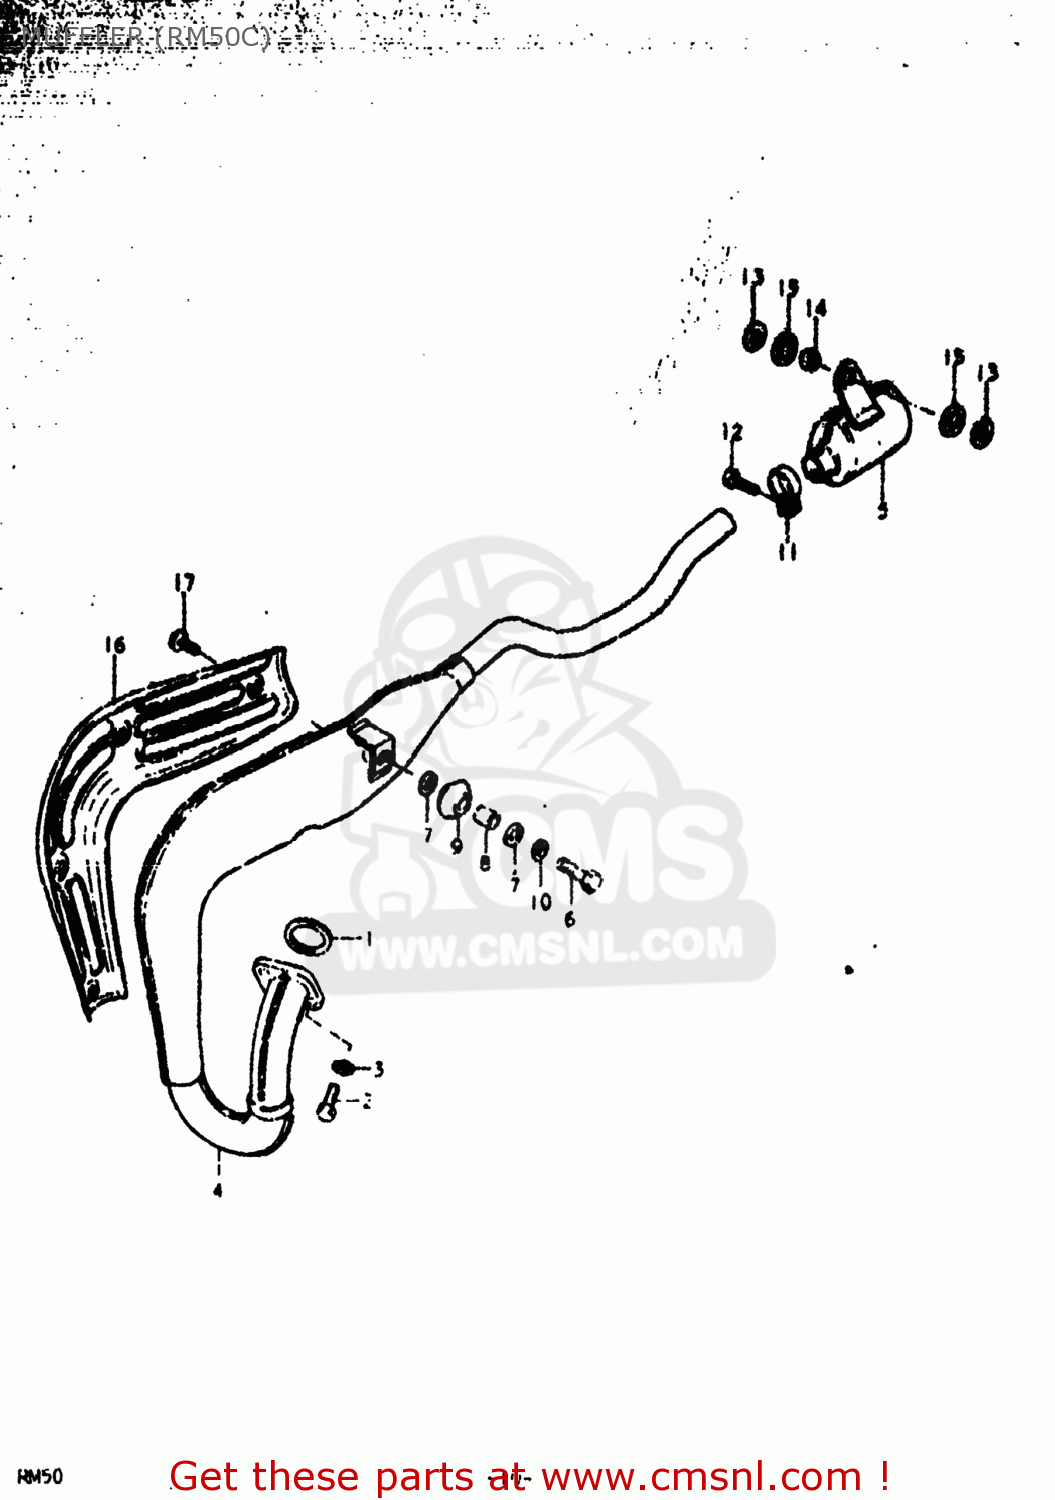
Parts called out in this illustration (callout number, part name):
1	GASKET,EXHAUST PIPE (NAS)
2	BOLT
3	LOCK WASHER
4	BODY,MUFFLER
5	BODY,MUFFLER
6	BOLT (8X30)
7	WASHER (8.7X22X2)
8	SPACER (8X12X15)
9	DAMPER,MUFFLER,FR
10	LOCK WASHER
11	CLAMP
12	BOLT(6X20)
13	WASHER
14	SPACER (8.6X13.8X9)
15	CUSHION
16	COVER,MUFFLER
17	SCREW
